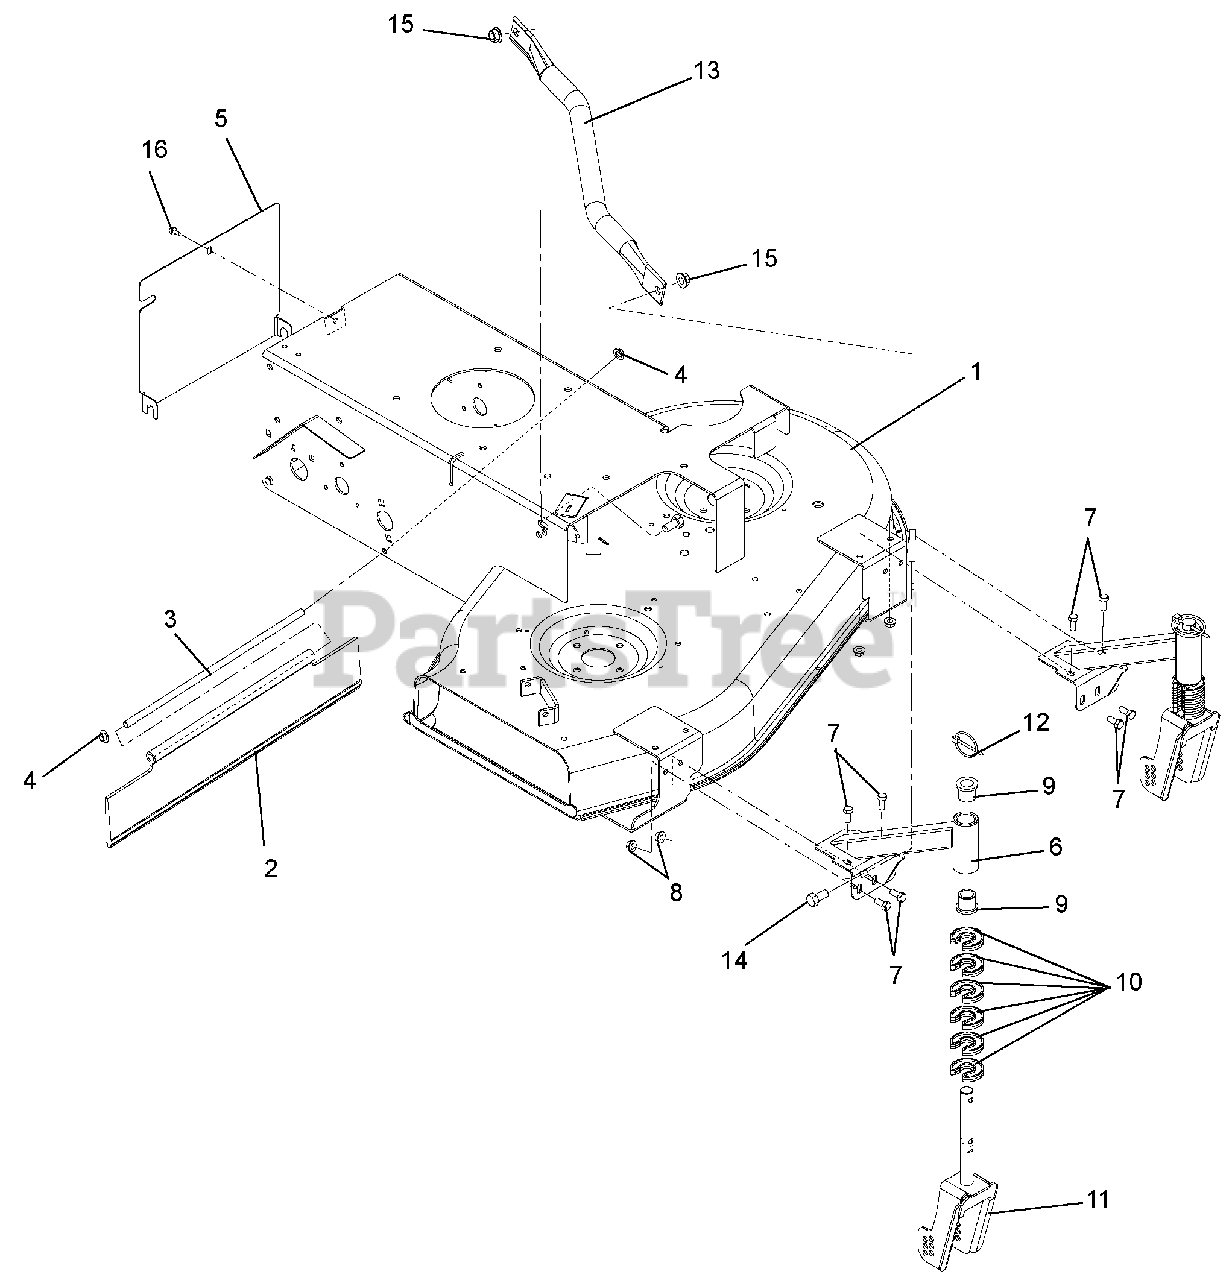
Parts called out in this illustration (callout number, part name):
1	CHASSIS, WAW 2010 (ARIENS)
2	GUARD - REAR - SWIVEL
3	ROD, TRAILING SHIELD
4	NUT-PUSH .312 DIA. PAL
5	COVER, REAR CHASSIS
6	ARM, CASTER (WLDMNT)
7	@BLT-HEX .31-18X.75 GR5 YWZC
8	@NUT-LK-TOP-FLG .31-18 YWZC
9	BUSHING, FLANGE .75X.75X1.0
10	CLIP-HOC FIXED
11	FORK, WAW CASTER (HEIGHT ADJ)
12	PIN, LYNCH - .25 X 1.25
13	TUBE-BRACE, DECK
14	@BLT-HEX .38-16X.75 GR5 YWZC
15	@NUT-LK-TOP-FLG .38-16 YWZC
16	@SCR-TAP .25-20X.50 HWH TR YWZ
